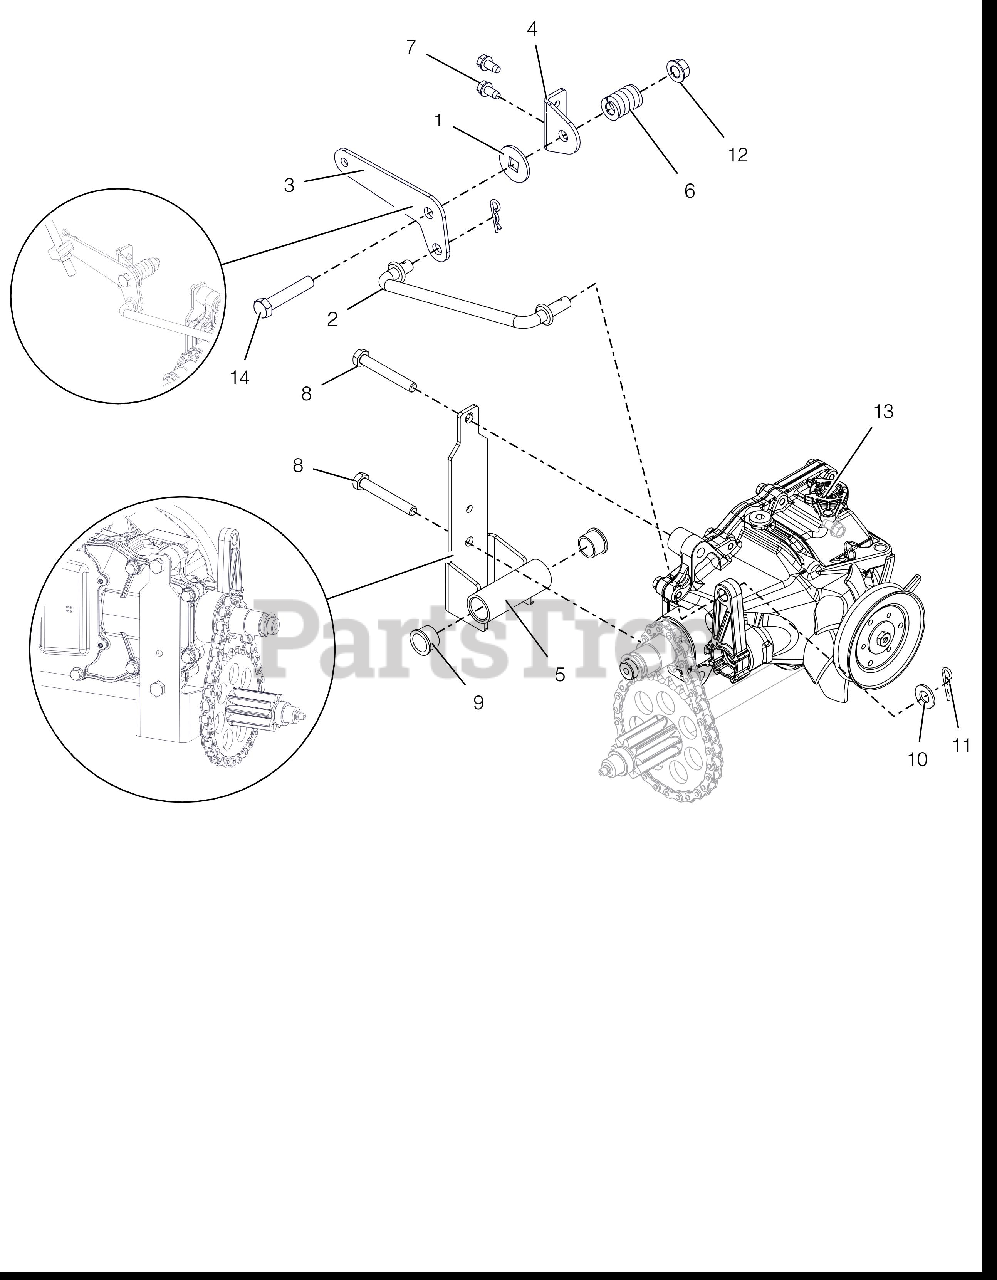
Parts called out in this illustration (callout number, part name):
1	FRICTION WASHER
2	ROD, HYDRO TRANS SHIFT
3	PIVOT, HYDRO TRANS SHIFT
4	BRACKET, HYDRO SHIFT PIVOT
5	TRANS MOUNT, TENSIONING, WHEEL
6	SG-COMP .187X.56X1.62
7	SCR-TAP .25-20X.50 HWH TR YWZ
8	@BLT-HEX .31-18X2.25 GR5 YWZC
9	BSHG-FLG .625X.750X.500X.875
10	@WSHR-FL-STL.406X.812X.065 YWZ
11	PIN-HAIR INT .08X.18X1.18 YWZC
12	@NUT-LK-TOP-FLG .38-16 YWZC
13	TRANSMISSION, HYDROSTATIC
14	@BLT-HEX .38-16X2.00 GR5 YWZC
